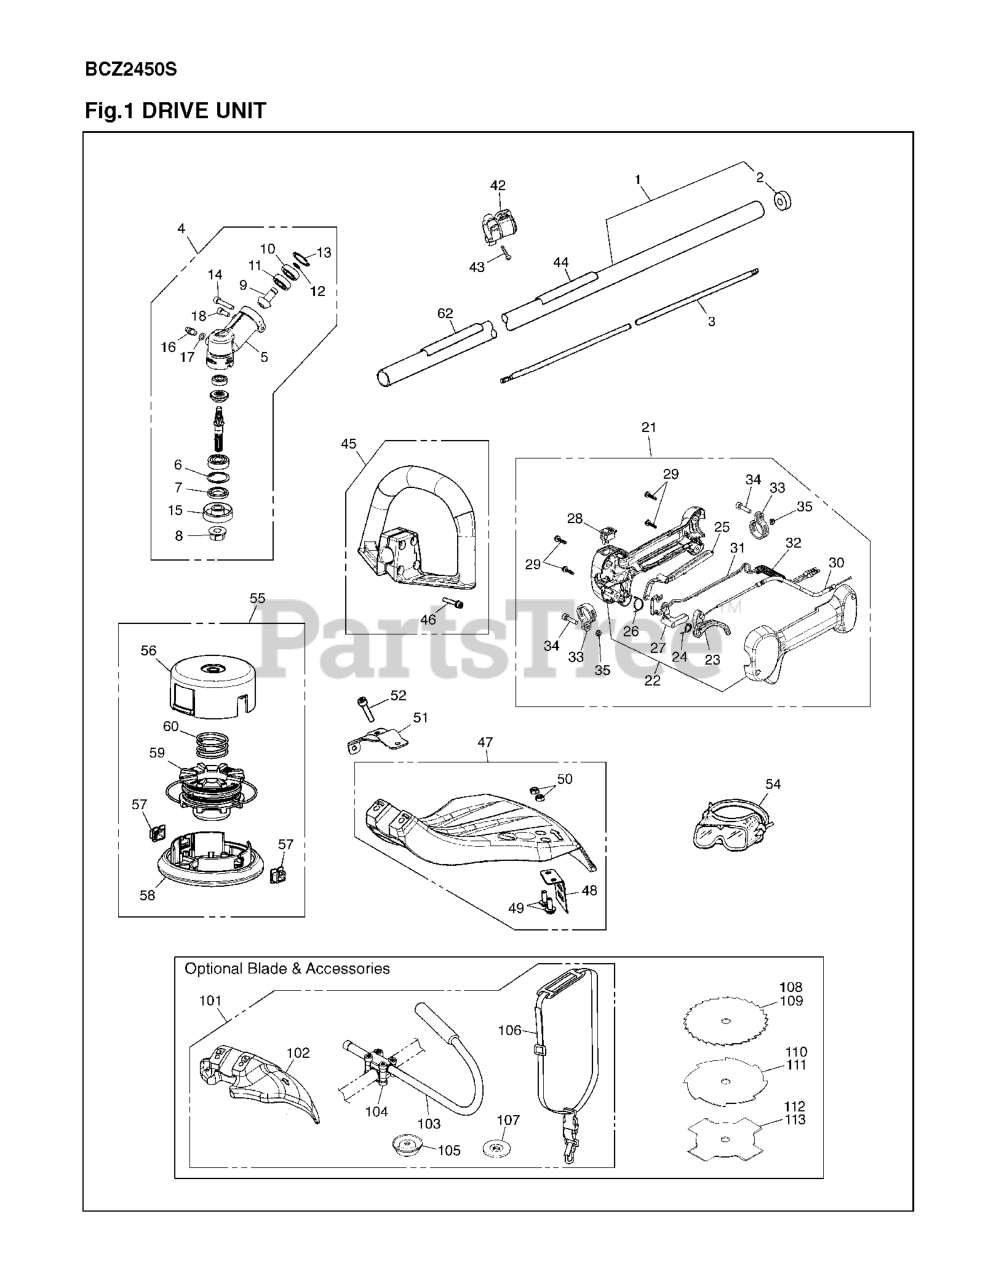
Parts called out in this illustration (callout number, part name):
1	PIPE COMP
3	SHAFT (RPLS -12212,936612210)
4	RP_GEARCASE ASSY.
5	%GEARCASE
6	RING,SNAP M26x1.2 RP-318013340
7	SEAL, OIL(RPLS 3565-13131)
11	BALL BEARING
12	RING
13	RP_RING
14	BOLT, TORX
15	HOLDER (A)
16	FITTING, GREASE
18	BOLT, TORX
21	GRIP-A
22	GRIP HALF SET
23	LEVER, THROTTLE
24	SPRING, THROTTLE
25	%LEVER SAFETY
26	SPRING
27	LEVER, JOINT
31	CORD - C
34	SCREW
35	NUT
42	HANGER COMP.
44	Name Plate Decal
45	HANDLE ASSY. (RPLS T319514001)
47	GUARD ASSY
49	SCREW
52	BOLT, TORX
54	GOGGLExxx (RPLS
56	CASE (RPL T318915112)
57	EYELET
58	COVER (RPLS T318915131)
59	HOLDER, CORD (RPLS T318915141)
62	LABEL CAUTON FOR BC
101	BLADE KIT BCZ 24/26/30 SERIES
102	GUARD
103	J-HANDLE
104	BRACKET ASSY.
105	COVER(10mm)(RPL280,-13280)
106	STRAP ASSY
107	HOLDER (B)
108	Brushcutter Blade, 22 Tooth 9"
109	Brushcutter Blade, 24 Tooth 9"
110	BLADE, 8
111	Brushcutter Blade, 8 Tooth 9"
112	BLADE, 8
113	Brushcutter Blade, 4 Tooth 9"
